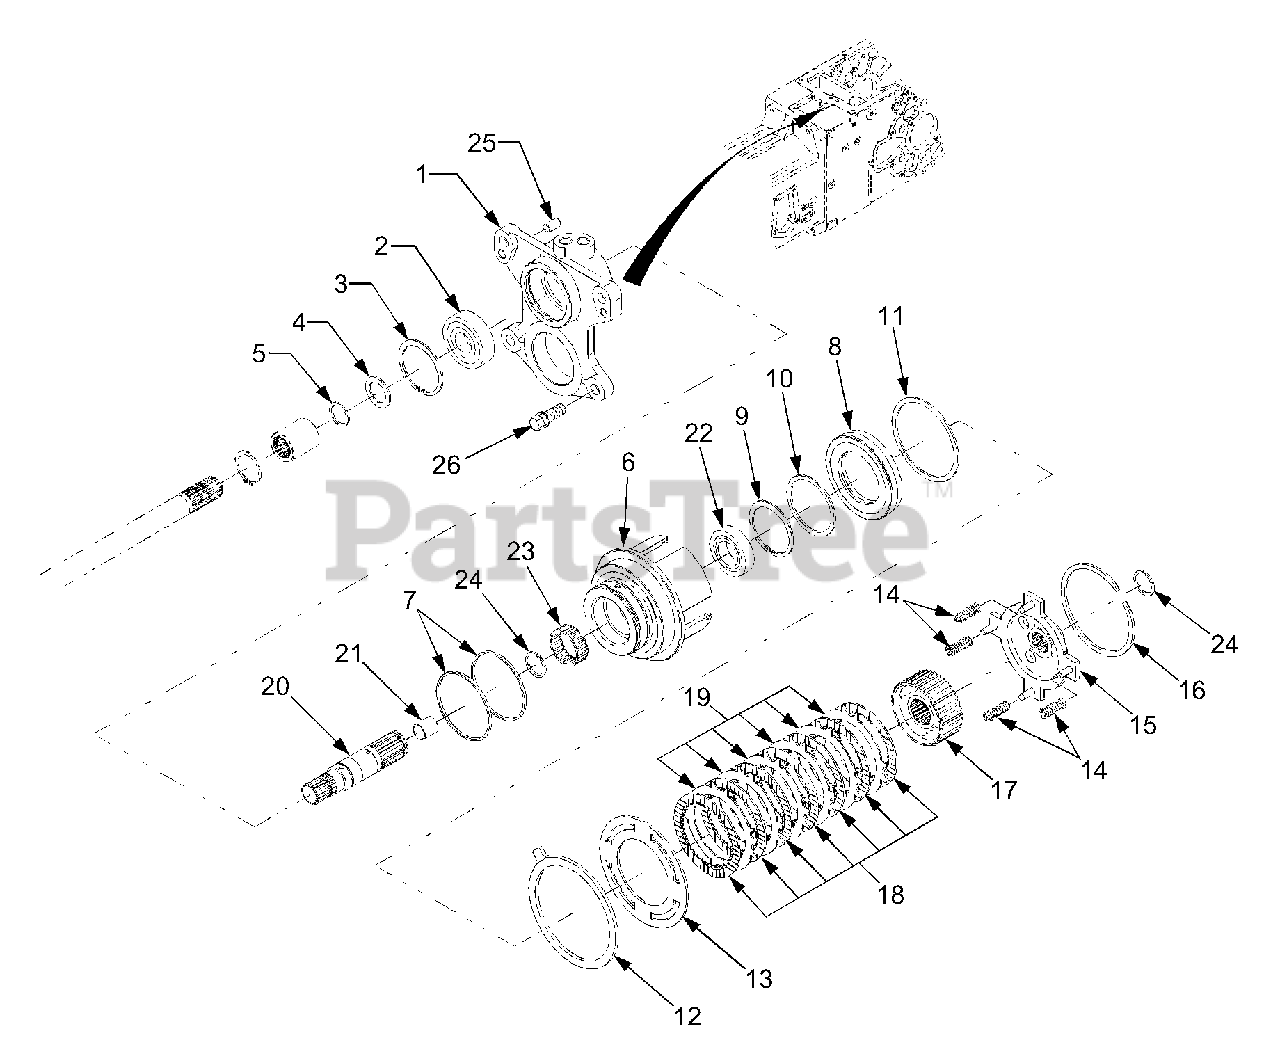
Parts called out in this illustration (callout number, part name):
1	Bracket, PTO Clutch
2	Bearing, Ball
6	Body, PTO Clutch
13	Plate, Return
15	Plate, Pressure
19	Plate, Clutch
20	Shaft, PTO Clutch
22	Bearing, Ball
23	Bearing, Needle
